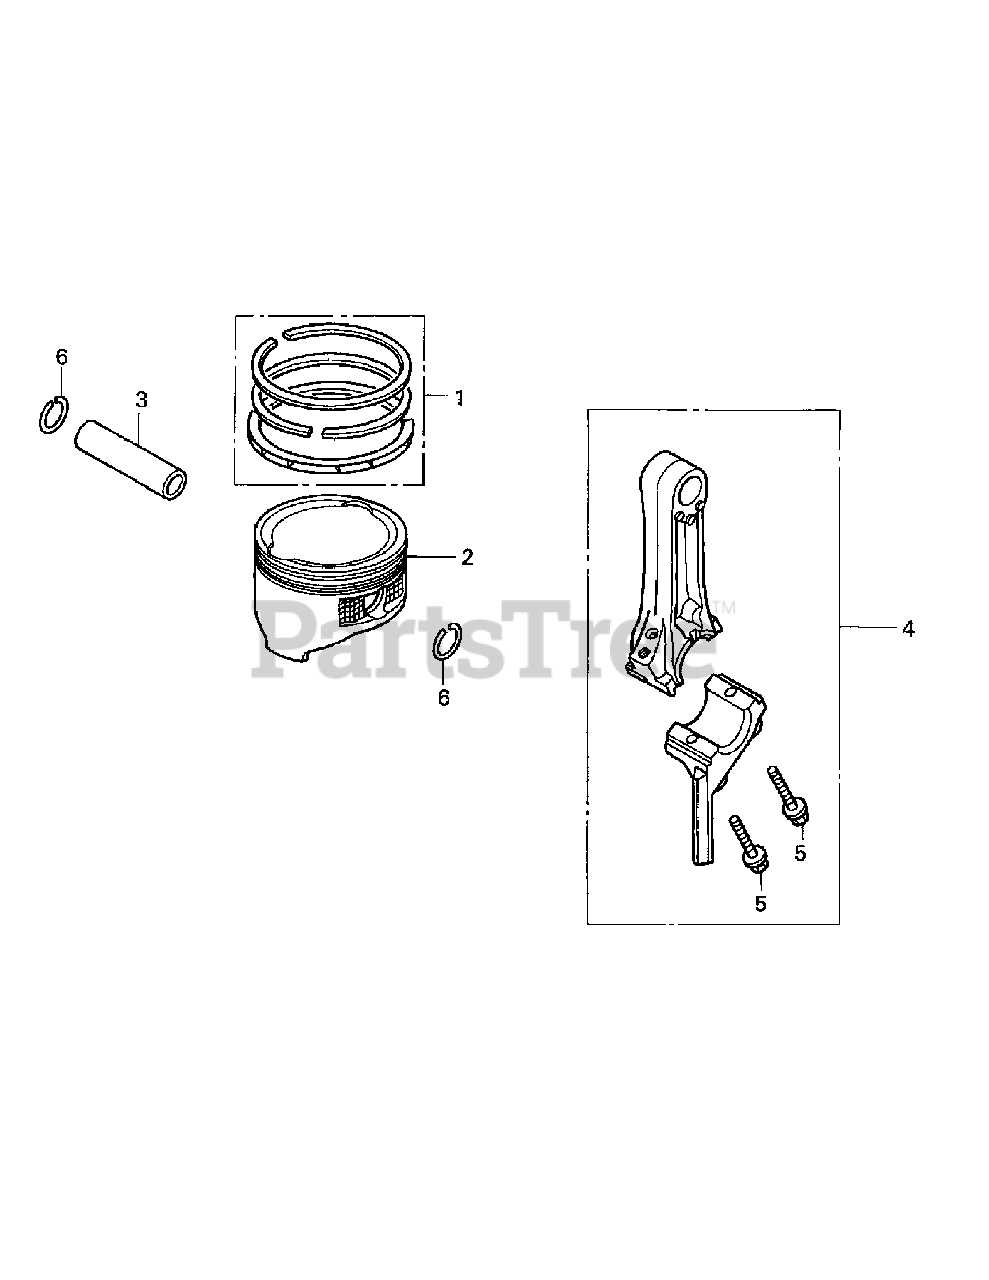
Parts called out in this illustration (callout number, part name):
1	Piston Ring Set, Riken
1	Piston Ring Set, Teikoku
3	Piston Pin
4	Connecting Rod Assembly
5	Connecting Rod Bolt
6	Piston Pin Clip, 13mm
